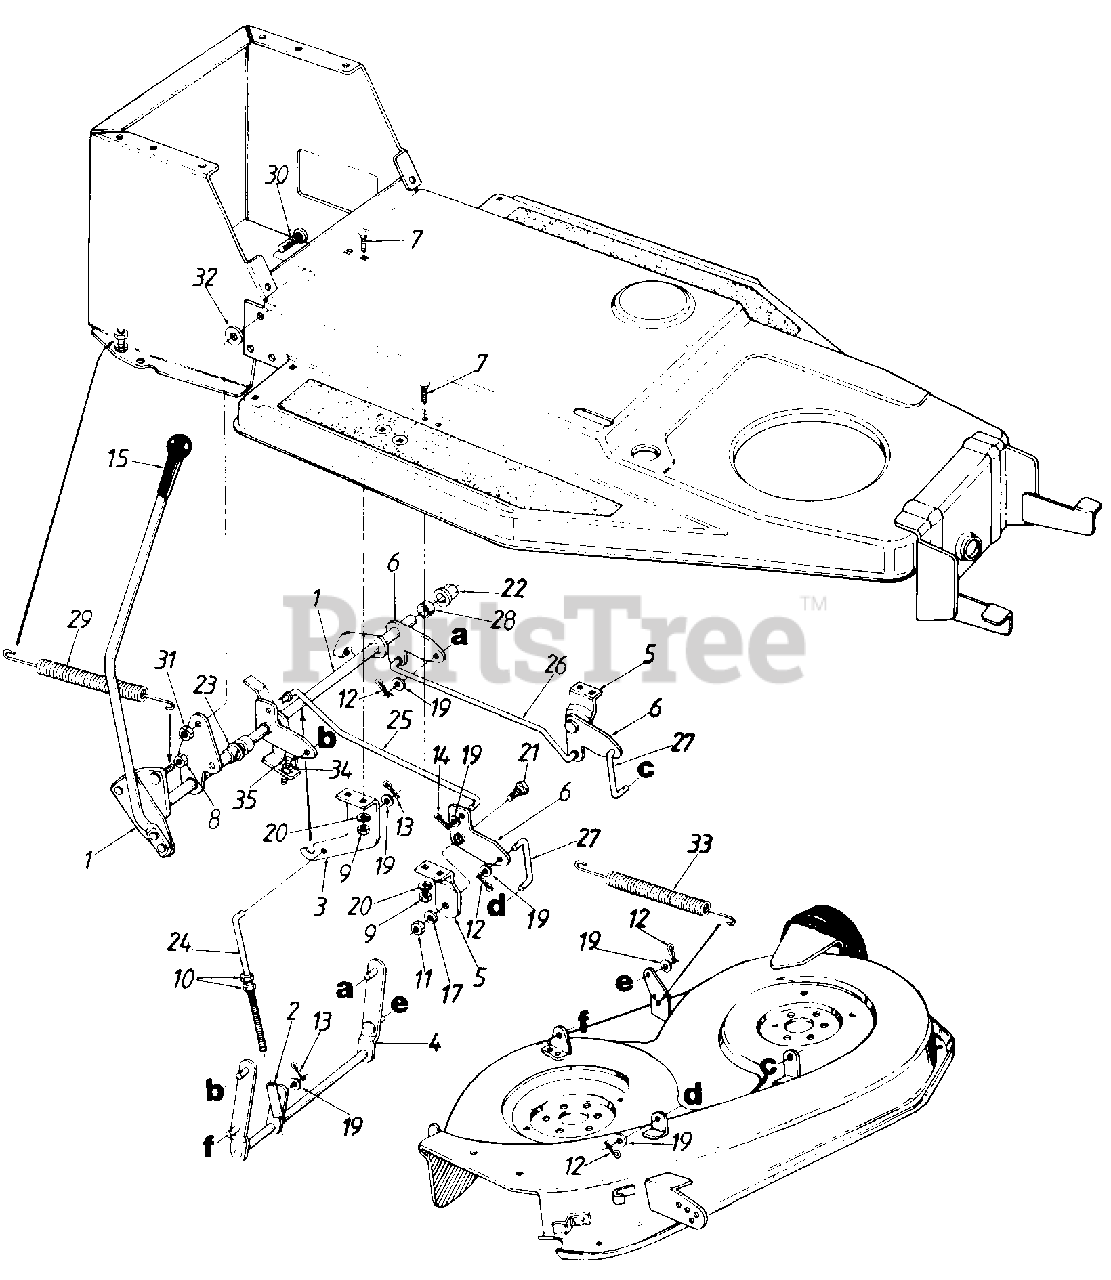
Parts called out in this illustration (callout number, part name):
1	Lift Shaft Ass'y.
2	Pivot Sleeve Ass'y.
3	Deck Lock Out 8rkt.
4	Stabilizer Ass'y.
5	Deck Lift Hanger
6	Deck Lift Float Brkt.
7	Carr. Bolt 1/4-20 X .62" Lg.
8	Hex L-Nut 5/16-18 Thd.
9	Hex Nut 1/4-20 Thd.
10	Hex L-Nut 3/8-24 Thd.
11	Hex Nut 3/8-16 Thd.
12	Intern. Cot-Pin 5/16" Dia.
13	Cot-Pin 1/8" Dia.
14	Cot-Pin 3/32" Dia.
17	L-Wash. 3/8" I.D.
19	Fl-Wash. .406" I.D. x .75" O.D.
20	L-Wash. 1/4" I.D.
21	Shld Bolt .625 Dia. x .425" Lg.
22	Hex Flange Brg.
23	Nyliner Flanged Brg.
24	J-Bolt 3/8-16 x 5.25" Lg.
25	Connecting Rod-R.H.
26	Connecting Rod-L.H.
29	Spring 8.65" Lg.
30	Ribbed Neck Bolt 3/8-24 x .80" Lg.
31	Hex Nut 3/8-24 Thd.*
32	Fl-Wash. 3/8" I.D.
33	Deck Spring 10.33" Lg.
34	Hex Nut 5/16-18 Thd.*
35	Hex Wash. Hd. Tap Scr. 5/16-18 x 1.0" Lg.
